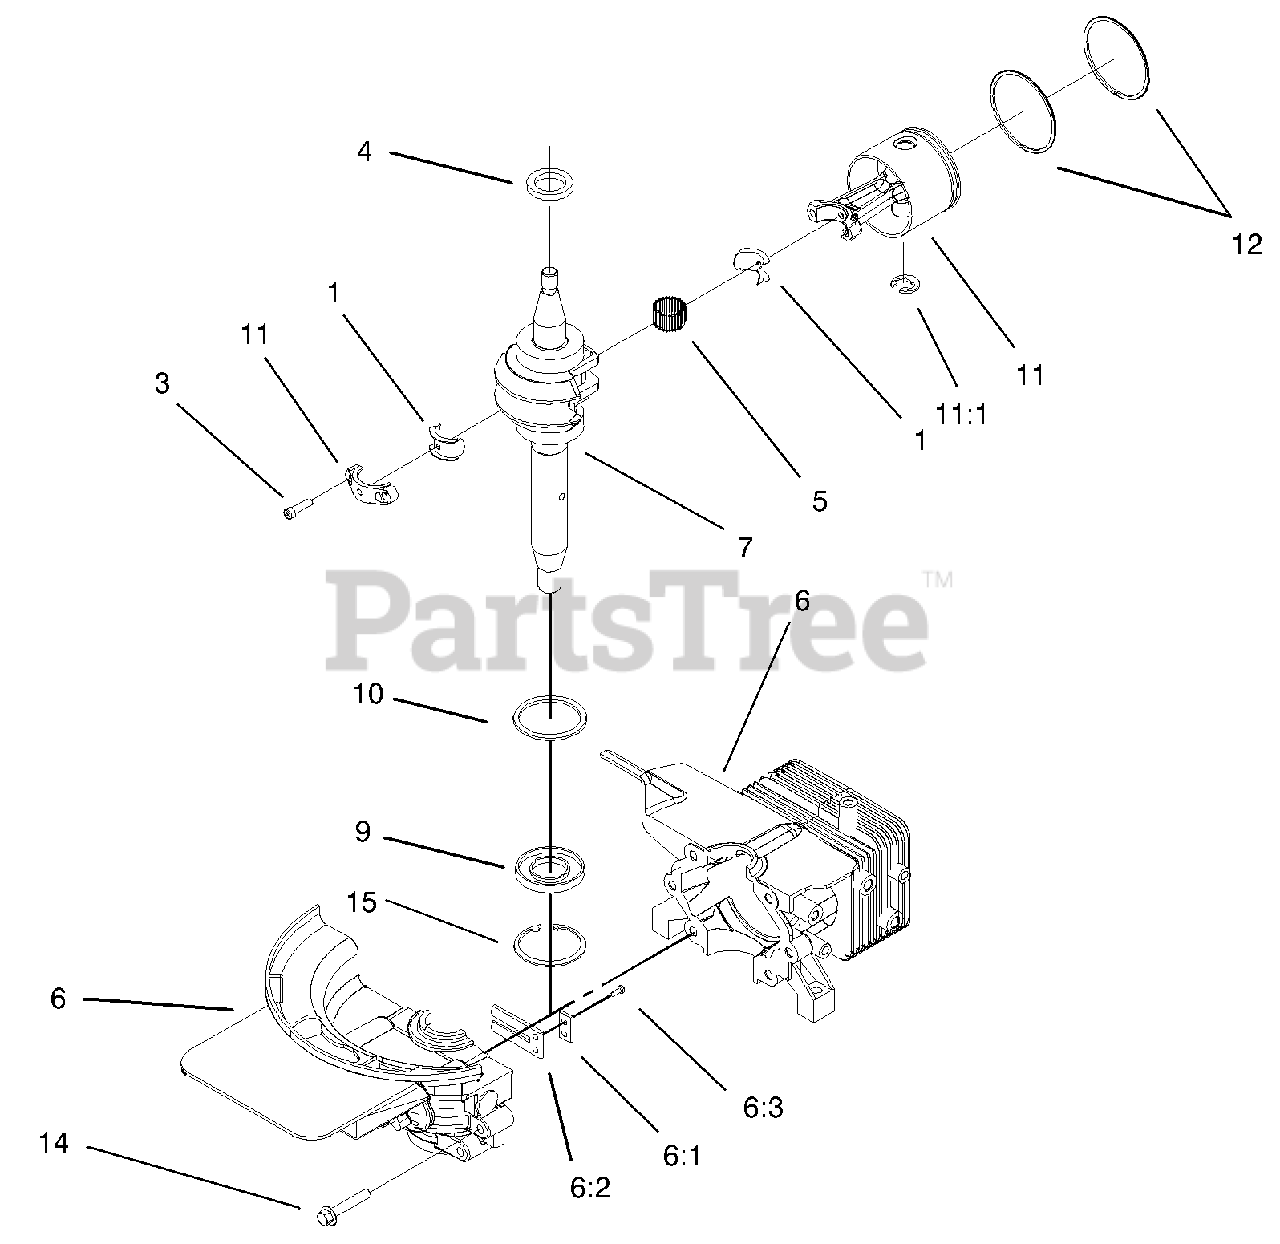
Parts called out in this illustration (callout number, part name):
1	LINER ASM
3	SCREW-HSH
4	SEAL-OIL
5	BEARING-NEEDLE
6	Cylinder And Crankcase ASM
6	CYLINDER AND CRANKCASE ASM
6:1	PLATE-BACKUP, REED
6:2	REED-CARBURETOR
6:3	SCREW-HH
7	CRANKSHAFT AND BEARING ASM
9	SEAL-OIL
10	RING-RETAINING, EXT.
11	Piston And Connecting Rod ASM
11:1	RING-RETAINING
14	SCREW-HHF
15	RING-RETAINING
